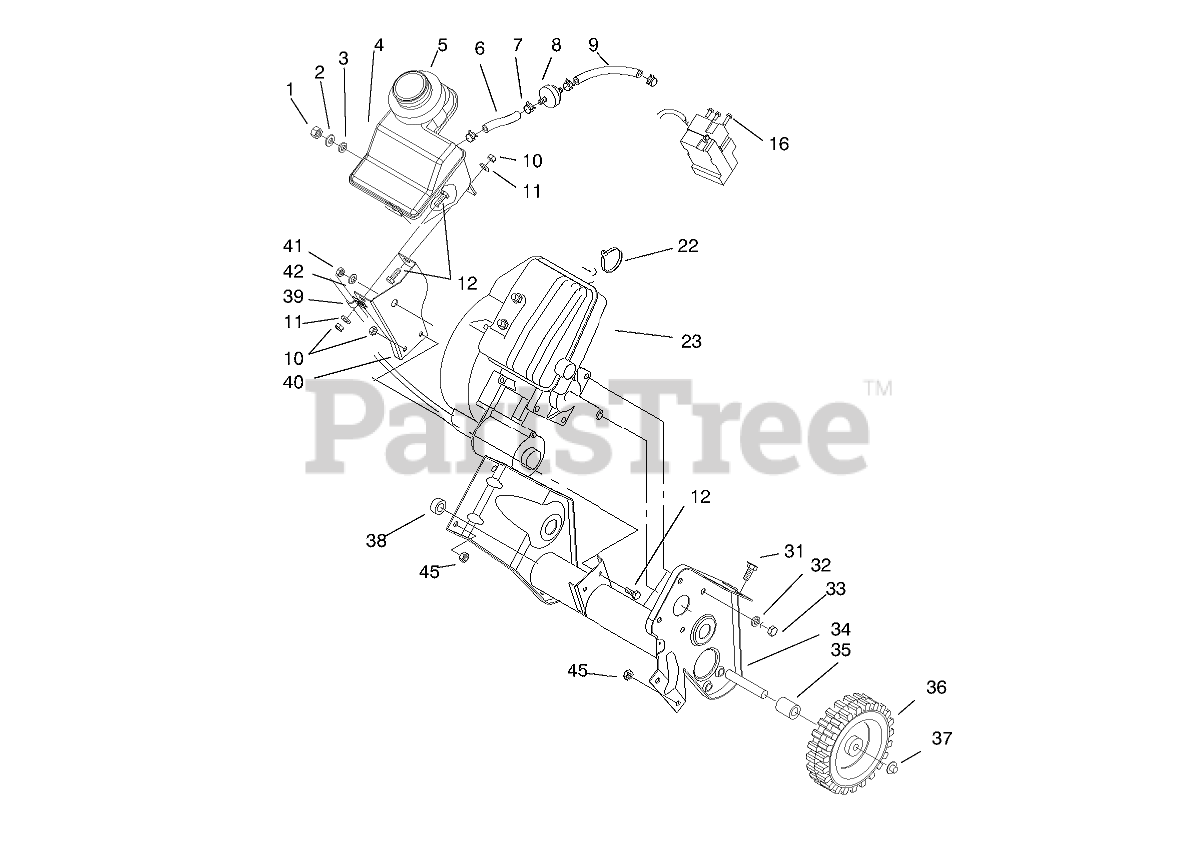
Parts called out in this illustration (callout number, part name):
1	NUT-LOCK, CONE
2	WASHER-PLAIN
3	GROMMET-RUBBER
4	Tank-Gas
5	SEAL-FOAM
6	LINE-FUEL
7	CLAMP-HOSE
8	FILTER-FUEL
9	HOSE-FUEL
10	NUT-LOCK, NI
11	WASHER-FLAT
12	SCREW-HH
16	SCREW-PLASTITE
22	TIE-CABLE
31	SCREW-HH
32	WASHER-BELLEVILLE
33	SCREW-HH
34	Frame
35	SPACER-WHEEL
36	WHEEL
37	NUT-PUSH
38	SPACER-WHEEL
39	CLAMP
40	Support-Recoil
41	NUT-LOCK, NI
42	WASHER-SUPPORT, ENGINE
45	NUT-LOCK, NI
